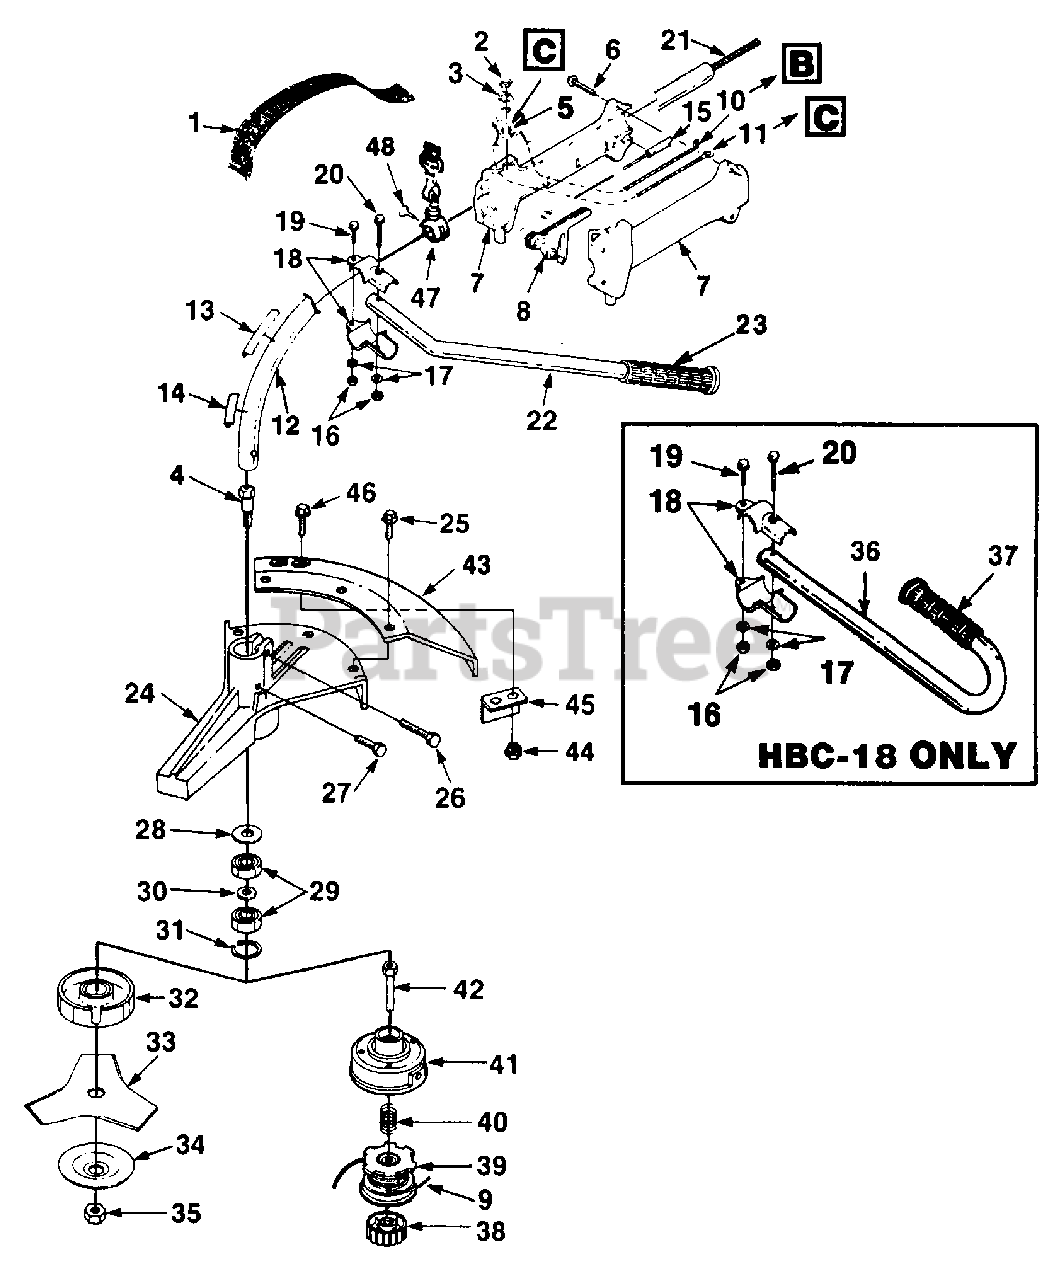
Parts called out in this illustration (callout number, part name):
1	HARNESS w/CONNECTOR
2	NUT
3	PLATE- Indicating
4	SHAFT- Spindle
5	SWITCH- Toggle
6	SCREW- Plastite (#8 x 3/4")
7	HANDLE GRIP ASSEMBLY
8	TRIGGER
9	LINE- Replacement (.080 Dia.) (100 Ft.)
10	LEAD- Electrical
11	LEAD- Ground
12	HOUSING- Driveshaft (ST-185BC)
13	DECAL- Starting Instructions
14	DECAL- Warning
15	CABLE- Throttle
16	NUT (1/4-20)
17	WASHER (1/4")
18	CLAMP- Handle bar
19	SCREW (1/4-20 x 1")
20	SCREW (1/4-20 x 1 1/2")
21	SHAFT- Flexible
22	HANDLE BAR
24	HOUSING- Lower bearing
25	SCREW (1/4-20 x 1/2")
26	SCREW (1/4-20 x 1")
27	SCREW (10-24 x 3/8")
28	WASHER- Thrust
29	BEARING- Ball
30	SPACER- Bearing
31	RING- Retaining
32	WASHER- Flange
33	BLADE- Tri-Arc (8")
34	WASHER- Cupped
35	NUT- Hex locking (R.H.)
36	HANDLE BAR ("J") (HBC-18)
38	RETAINER- Spool (R.H Thread)
39	SPOOL & STRING (Dual Line)(ST-185BC)
40	SPRING- Compression
41	HOUSING & EYELET (Dual Line)
42	CONNECTOR- Drive
43	DEFLECTOR- Grass
44	NUT (10-32)
45	BLADE- Cut-off
46	SCREW (10-32 x 3/8")
47	BRACKET- Hanger
48	SCREW- Thumb (10-24 x 1/2")
